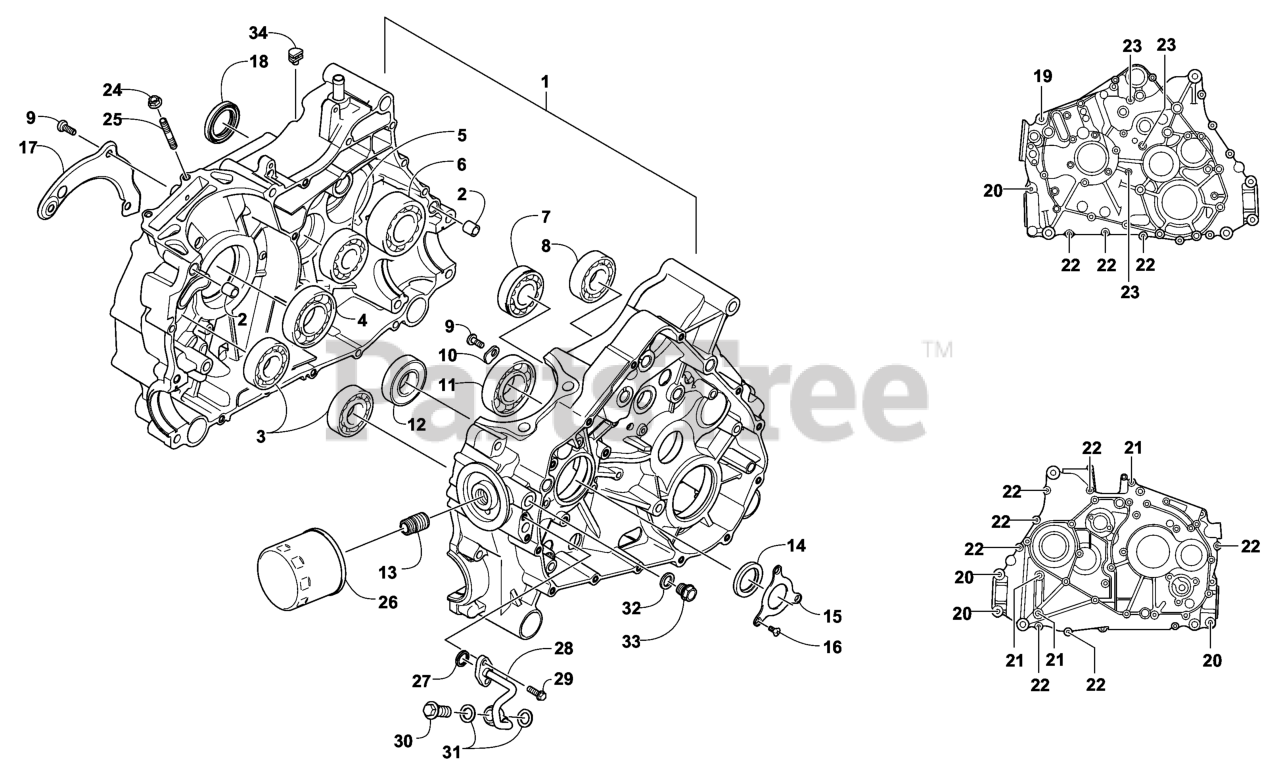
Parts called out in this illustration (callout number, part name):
2	PIN-DOWEL
3	BEARING-BALL, RADIAL
4	BEARING-BALL, RADIAL
5	BEARING-BALL, RADIAL
6	BEARING-BALL
7	BEARING-BALL, RADIAL
8	BEARING-BALL, RADIAL
9	SCREW-PPH
10	RETAINER-BEARING
11	BEARING
12	BEARING-CONRAD
13	UNION-OIL FILTER
14	SEAL-OIL, CRANKSHAFT
15	RETAINER-CROSS, OIL SEAL
16	SCREW-PFH
17	PLATE-OIL GUIDE, RIGHT
18	SEAL-DRIVESHAFT
19	BOLT-FLANGE
20	BOLT-FLANGE
21	SCREW-HFH
22	BOLT-FLANGE
23	SCREW-HFH
24	NUT-HHF
25	BOLT-STUD
26	Filter, Oil
28	PIPE-COMP, OIL
29	BOLT-FLANGE
31	SEALING-ASHER B OIL PIPE
32	WASHER-COMPRESSION
33	PLUG-CASE
34	GROMMET
